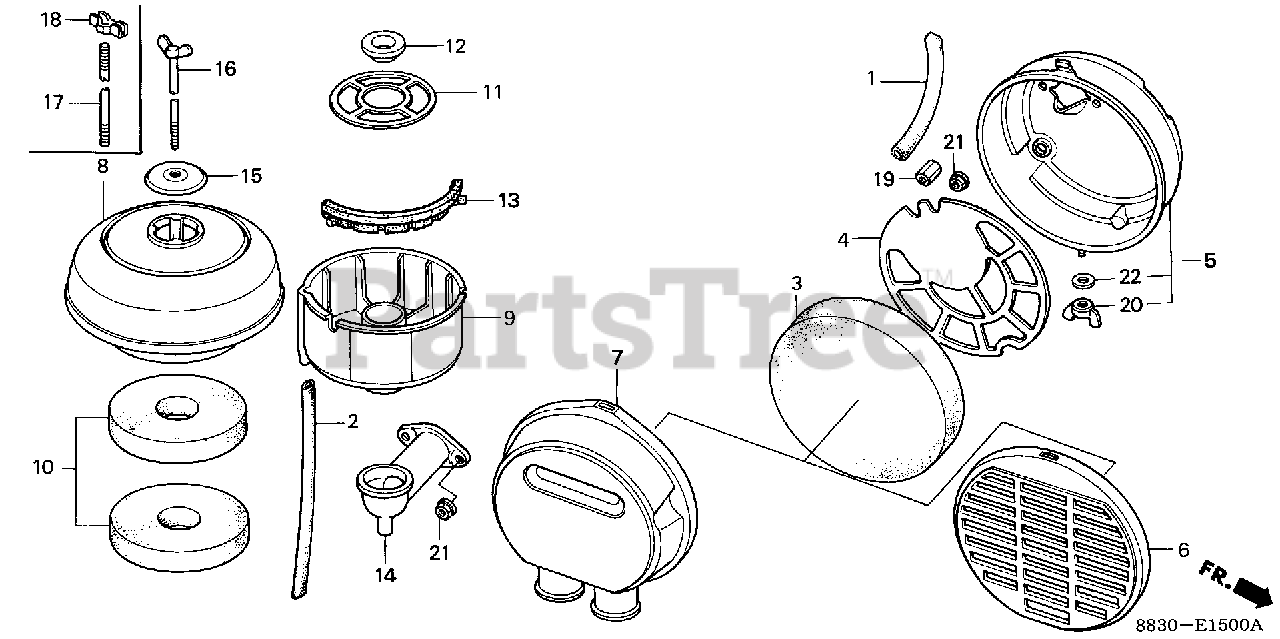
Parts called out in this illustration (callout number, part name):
2	TUBE, BREATHER
7	COVER, AIR CLEANER
8	BODY, CLEANER
9	PAN, AIR CLEANER OIL
10	ELEMENT, AIR CLEANER
11	GRID, AIR CLEANER
12	COLLAR, AIR CLEANER (NOT AVAILABLE)
14	ELBOW, AIR CLEANER
15	CAP, AIR CLEANER
16	BOLT, AIR CLEANER
21	NUT, FLANGE (6MM)
